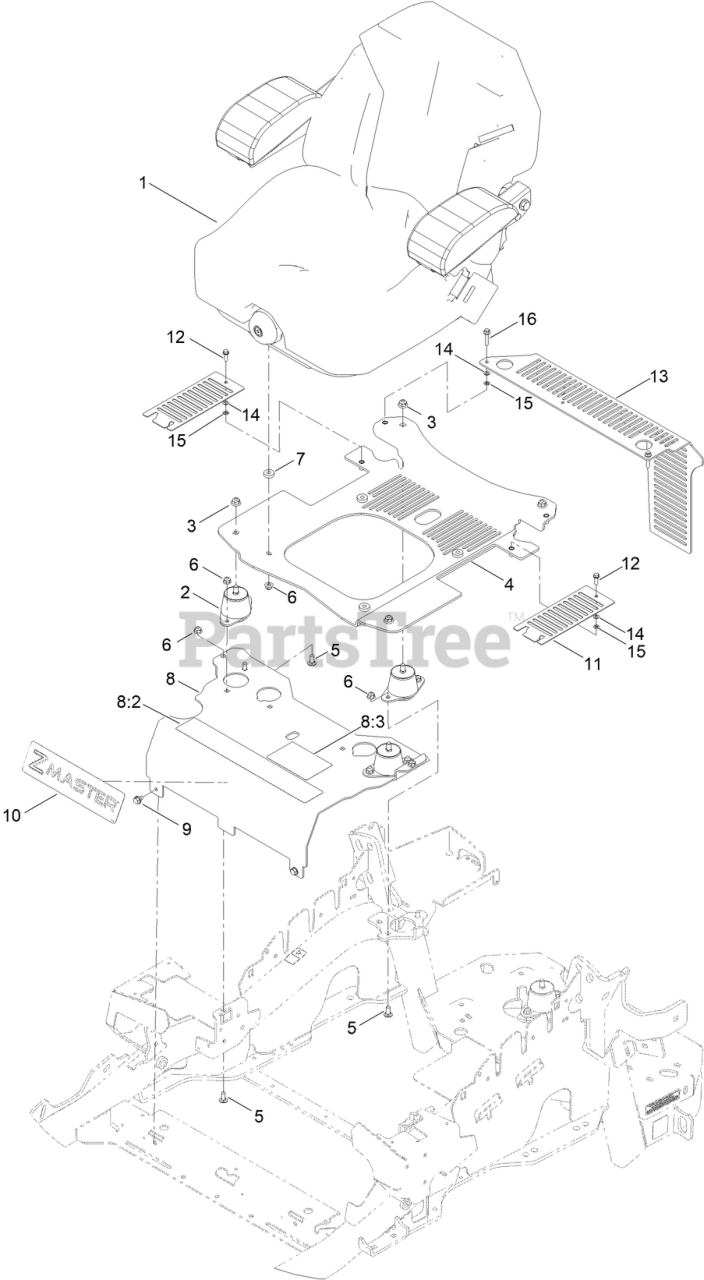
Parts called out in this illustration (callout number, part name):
1	SEAT-SUSPENSION
2	ISOLATOR-SEAT
3	NUT-HF, NI
4	SEAT BASE ASM
5	SCREW-CARR
6	NUT-HF, NI
8	MOUNT-SEAT
8:2	DECAL-CONSOLE
8:3	DECAL-SERVICE AID
9	SCREW
10	DECAL-CONSOLE
12	SCREW-HWH
13	GUARD-CE
14	WASHER-FLAT
15	PUSHNUT-RETAINER, BOLT
16	SCREW-HHF
